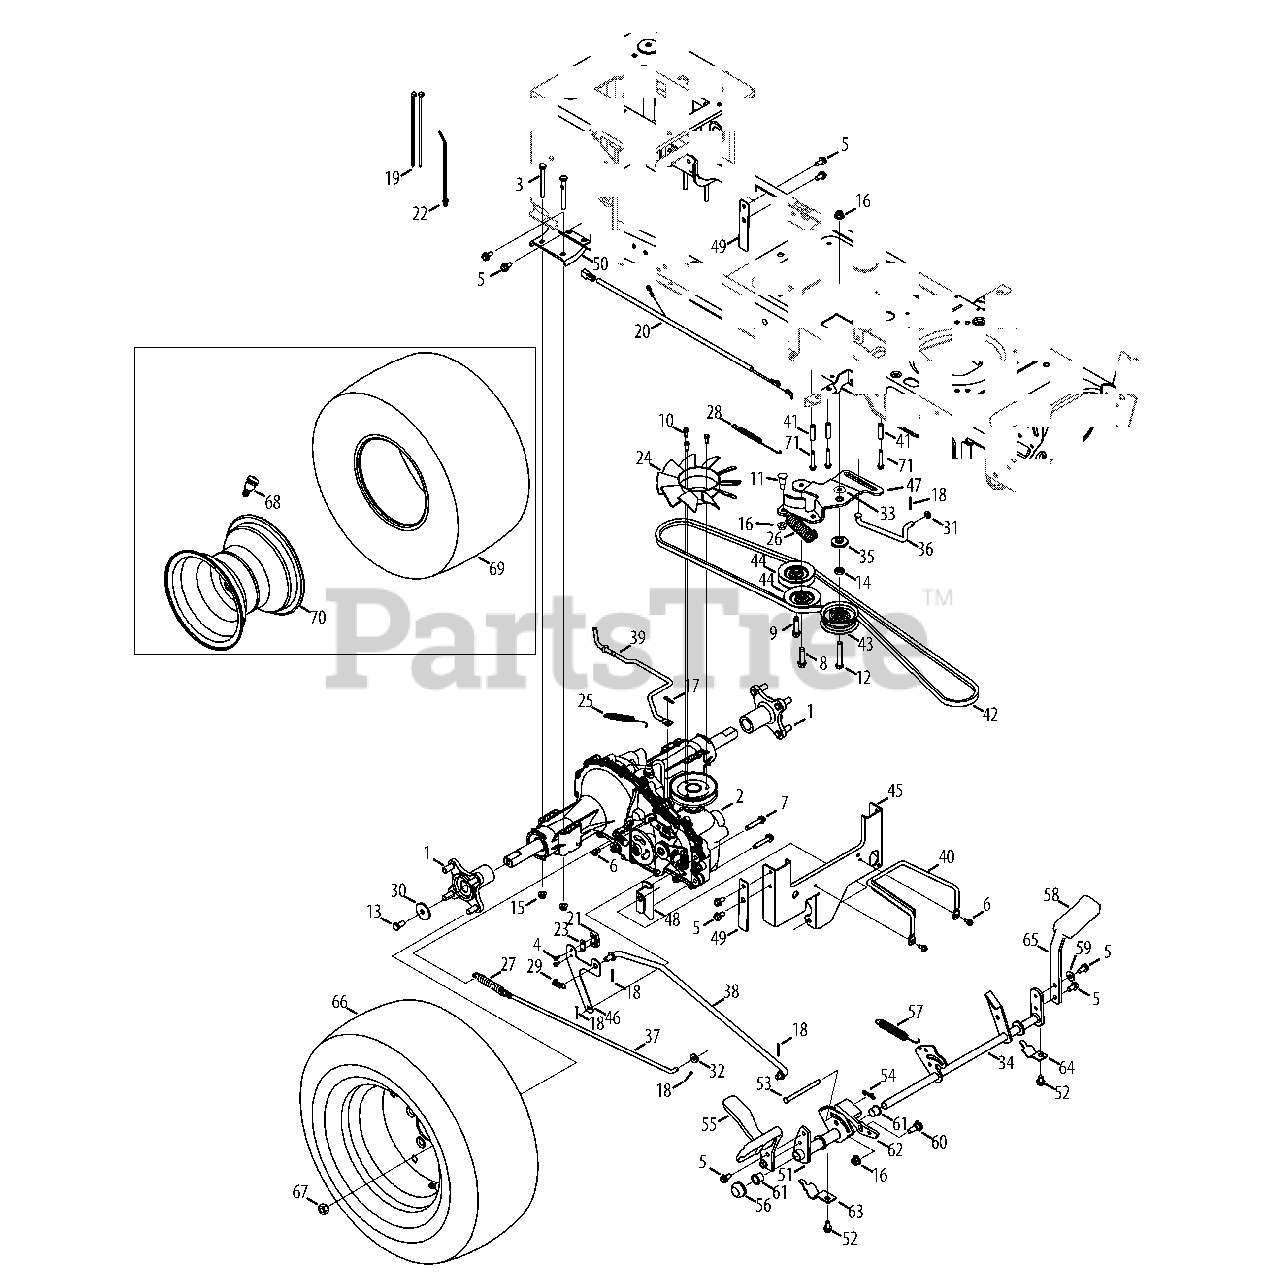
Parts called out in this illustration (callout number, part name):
1	Wheel Assembly Hub
2	Transmission
3	Hex Screw, 5/16-18:3.00
4	Screw, #8-18:0.500
5	Taptite Screw, 5/16-18:.750
6	Taptite Screw, 1/4-20:0.500
7	Taptite Screw, 5/16-18:1.750
8	Taptite Sems Screw, 3/8-16:1.500
9	Taptite Sems Screw, 3/8-16:1.875
10	Screw, #12-24:0.625
11	Scr, Shldr, .50 x .685 3/8-16
12	Hex Screw, 3/8-16:2.25
13	Hex Screw, 3/8-16:.750
14	Jam Nut, 7/16-20
15	Flangelock Nut, 5/16-18
16	Flangelock Nut, 3/8-16
17	Cotter Pin, .072 DIA. x 1.13 LG
18	Cotter Pin, 3/32:1.0
19	Cable Tie, 3/16 x .05 x 7.4
20	Jumper Harness
21	Short Spring Switch
22	Push Mount Cable Tie 7.5 LG
23	Insulator Nut Plate
24	Blade Fan
25	Extension Spring, .50 DIA x 5.0 LG
26	Extension Spring, 1.00 DIA x 4.75
27	Extension Spring, .59 OD x 4.00 LG
28	Extension Spring, .38 DIA x 5.6
29	Extension Spring, .375 OD x 1.44 LG
30	Flat Washer, .390 x 1.500 x .134
31	Flat Washer, .330 x .630 x .0635
32	Flat Washer, .344 x .750 x .120
33	Washer, Flat, .385 x 1.0 x .030
34	Brake Control Assembly
35	Shoulder Spacer, 1.375 x .380 x .183
36	Footpedal Bypass Transmission Rod
37	Brake Rod
38	Control Rod
39	Disengage Rod
40	Belt Keeper, 5/16
41	Spacer, 260 x .372 x 1.420 LG
42	V Belt, 4L x 77.0
43	Flat Idler Pulley, 2.75 OD
44	V Idler Pulley, 3.06
45	Torque Bracket
46	Switch Bracket
47	Center Idler Bracket
48	Deck Bracket
49	Plate Bracket
50	Axle Bracket
51	Hydro Pedal Bracket Assembly
52	Taptite Screw, 5/16-18:0.625
53	Clevis Pin, 5/16 x 3.985
54	Bow-Tie Cotter Pin
55	Control Pedal
56	Push Cap
57	Extension Spring, .63 DIA x 4.95 LG
58	Brake Pedal Pad
59	Bell Washer, .340 x .872 x .060
60	Shoulder Bolt, .500 x .270:3/8-16
61	Flange Bearing, .630 ID x .695 OD x .60
62	Cruise Latch
63	Pedal Support Bracket
64	Pedal Support Bracket, 5/8
65	Brake Pedal Bracket
66	Wheel Assembly
67	Lug Nut, 7/16-14
68	Air Valve
70	Rim Assembly
71	Taptite Screw, 1/4-20:1.750
